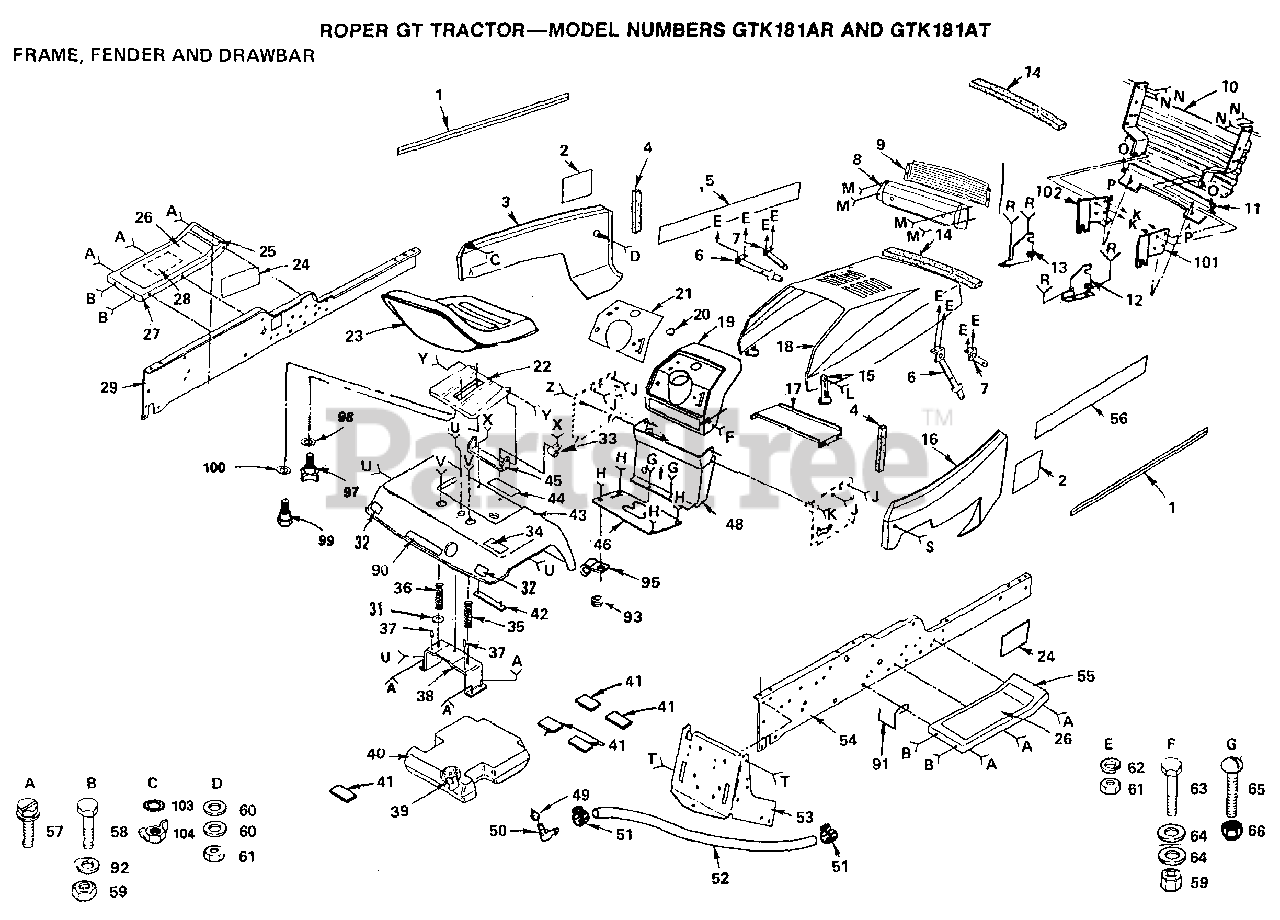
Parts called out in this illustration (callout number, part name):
4	FOAM STRIP T
9	LENS LT
12	SUPPORT RH YTH
13	SUPPORT LH YTH
14	FOAM STRIP T
15	HOOD LATCH T
17	SUPPORT-BATTERY
20	PLUG-DASH T
21	DECAL-DASHBOARD (GTK181AT ONLY)
25	DECAL T
27	FOOTREST LH YT
28	DECAL T
31	SHIM WASHER T
32	REFLECTOR-TAIL YT
33	CLIP T
34	DECAL-CAUTION
35	SPRING-COMPRESSION R.H.
37	NUT-PUSH YT
41	PAD-SPACER LT
46	COVER GATE SHIFT
46	CVR SHAFT GATE
48	DASH ASSEMBLY
49	BUSHING OUTLET T
50	FUEL TANK STEM GT
57	SCREW
60	WASHER 9/32 X 3/4 X 16 GA..
63	BOLT
64	WASHER
65	SCREW
91	BELT RETAINER GT
92	WASHER
93	GROMMET T
97	"KNOB 1/2"" YT"
98	WASHER
99	BOLT T
101	SUPPORT RH YTH
102	SUPPORT LH YTH
103	LOCKWASHER GT
